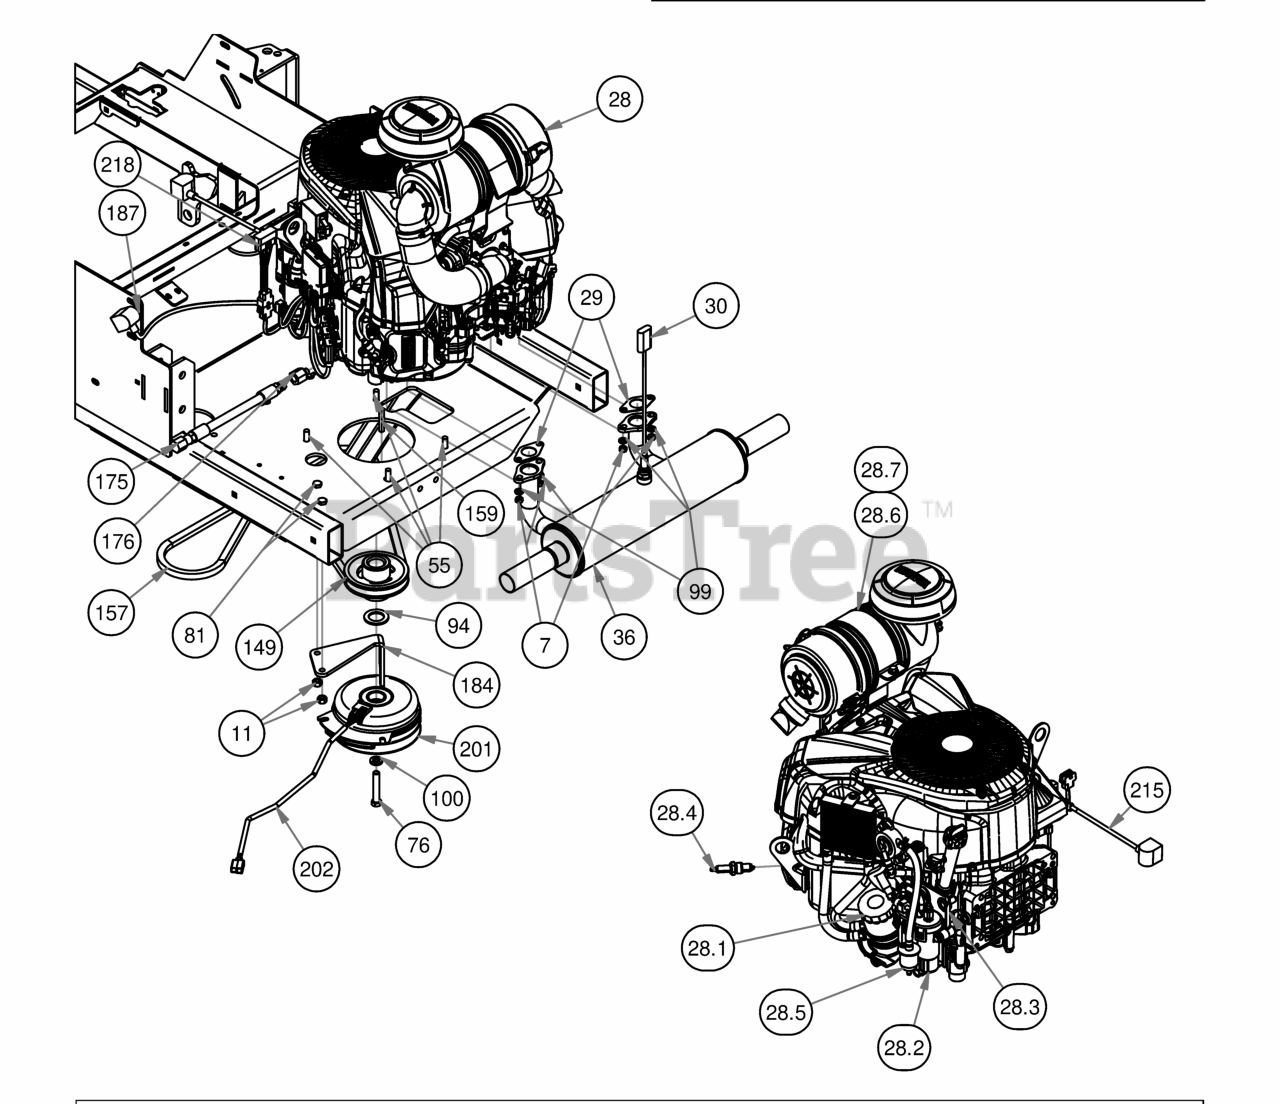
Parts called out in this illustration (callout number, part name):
7	M8-1.25 Zinc Nut
11	3/8" Hex Nut
28	Yamaha 33hp EFI Engine
28.1	Oil Filter
28.2	Yamaha Fuel Pump
28.3	Yamaha Fuel Pump Bracket
28.4	Yamaha Spark Plug
28.5	Yamaha Fuel Filter
28.6	Canister Air Filter- Outer
28.7	Canister Air Filter- Inner
29	Exhaust Gasket for yamaha
30	O2 Sensor for Yamaha
36	Muffler for 27Hp Yamaha
55	3/8 x 1 1/8 bolt
76	7/16" x 2 1/2" Hex Bolt
81	3/8" x 1" Hex Bolt
94	1 1/8" Flat Spacer
99	5/16" Lock Washer
100	7/16" Lock Washer
149	4 3/4 Motor Pulley
157	2019 Rogue Pump Belt 68"
159	1/4 x 2 Square key Stock
175	Oil drain Hose for Yamaha
176	Oil Drain Adapter for Yamaha
184	PTO Engager Holder
187	24" Red Battery Cable
201	Clutch Assembly
202	Clutch Pigtail
203	2019 Veritical Suspension Frame
215	Starter Cable
218	2019 Harness Adaptor - Vanguard 37 EFI Vert/Horiz
